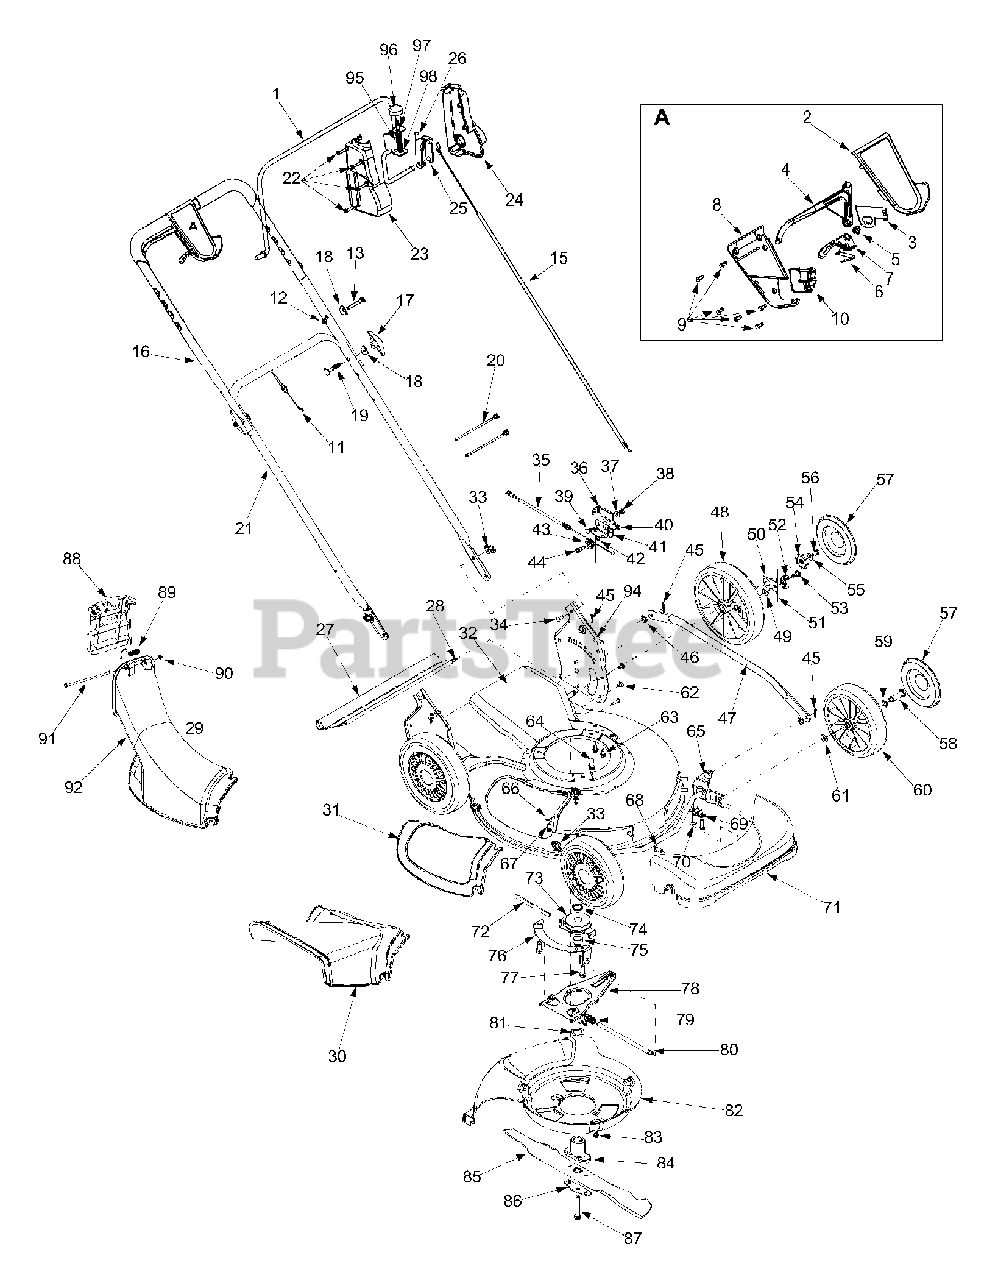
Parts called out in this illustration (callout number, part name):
2	Upper Control Handle
3	6 Spd. Rack Cable Bracket
4	Control Lever
5	Gear Insert
6	Shift Lever Spring
7	6 Speed Shift Lever
8	Lower Control Housing
9	C Sunk Tap Screw #10 x .75 Lg
10	Cable Mounting Cap
11	Drive Cable 51.0
12	Hex Lock Nut 1/4-20 Gr. 8
13	Hex Hd. Cap Screw 1/4-20 Gr. 5
15	Control Cable 46"
18	Saddle Washer .320 ID x .830 OD
19	Carriage Bolt 5/16-18 x 2.0
20	Cable Tie
22	Hi-Low Screw
23	Control Cover RH
24	Control Cover LH
25	Lever
26	Torsion Spring
27	Trail Shield
28	Trail Shield Wire
29	Chute Assembly
30	Side Discharge Chute
31	Mulch Cover
33	Wing Nut
34	Carriage Bolt 1/4-20 x .75
35	6 Speed Cable
38	Hex Nut 1/4-20
39	Carriage Screw 1/4-20 x .50
40	Hex Nut 1/4-28
43	Roller Cable
44	Shoulder Screw .375 ID x 1/4-14
45	Cotter Pin
46	Bowed Washer
48	Wheel 9 x 2
49	Top Lock Tab Weld Nut 1/4-20
50	Ratchet Pawl Plate
51	Plastic Spring Ratchet
52	Pawl RH
53	Shld Screw .340 ID x .285 OD
54	Wheel Rachet
55	Bell Washer .265 ID x .75 OD
56	Hex Cap Screw 1/4-20 x .620
57	Hubcap
58	Shoulder Screw .498 x 1.445
59	Wave Washer .510 ID x .750 OD
60	Wheel 8 x 2
61	Spring Washer .401 ID x .870 OD
62	Screw 1/4-14 x .500
63	Screw 1/4-14 x .625
64	Hex Washer Screw 3/8-16 x 1.0
66	Flat Washer .344 ID x .62 OD
67	Carriage Screw 1/4-20 x .75
68	Torx Screw
69	Block Bushing
70	Hex Washer Screw
71	Front Axle Cover
72	Belt 3/8 x 39.24
73	Pulley Assembly
74	Sleeve Spacer .88 ID x 1.13 OD
75	Sleeve Spacer .88 ID x 1.00 OD
77	Screw 3/8-18 x 1.0
80	Pivot Shaft
81	Wave Washer 1.38 ID x .88 OD
82	Baffle
83	Screw 1/4-20 x 3.75
84	Blade Adapter Kit
85	21" Mulching Blade
86	Blade Bell Support
87	Hex Bolt 3/8-24 x 2.5
88	Chute Door
89	Torsion Spring
90	Push Cap
91	Pivot Rod
92	Discharge Chute
96	Button
98	Retention Spring
